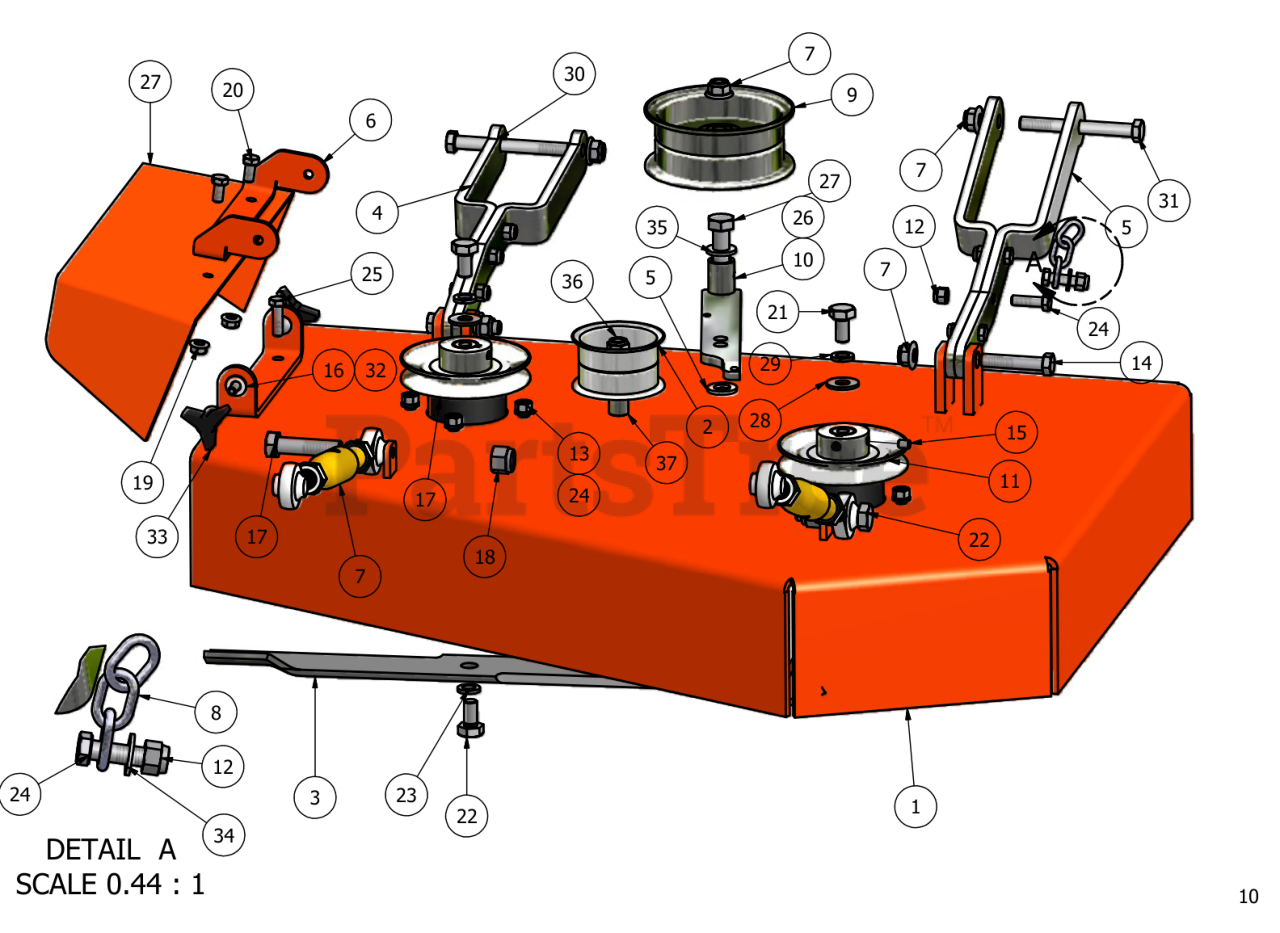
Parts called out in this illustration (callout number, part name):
1	36" Inch ZT Deck
2	36" ZT Idler Pulley
3	36" Fusion Blade
4	Deck Support Arm (Left)
5	Deck Support Arm (Rigth)
6	Discharge Chute Bracket
7	Turnbuckle
9	5 3/4" Flat Idler Pulley
10	Deck Idler Arm
11	5" Deck Pulley
12	3/8 Nylock Nut
13	3/8" Hex Bolt
14	1/2"x2 1/2" Hex Bolt
15	3/8" Set Screw
16	.360 ID Plastic Washer
17	5/8" x 2 1/2" Hex Bolt
18	5/8" Nylock Nut
19	3/8" Flange Nut
20	3/8" x 3/4" Hex Bolt
21	1/2"x 1 1/2" Fine Threaded Bolt
22	5/8" x 1 1/2" Fine Threaded Bolt
23	5/8" Lock Washer
24	3/8" Lock Washer
25	3/8" x 1 1/4" Hex Bolt
26	5/8" ID × 1 1/8" Brass Bushing
27	5/8" x 4" Hex Bolt
28	1/2" Cup Washer
29	1/2" Lock Washer
30	1/2" Brass Bushing
31	1/2"x4 1/2" Bolt
32	5/16"x 1" Carriage Bolt
33	5/16" Knob
34	3/8" Washer
35	.635 Nylon Washer
35	3" Chain Assembly
36	1/2" Flange Lock Nut
36	3/8" Fiber Washer
37	2.313 Spacer
